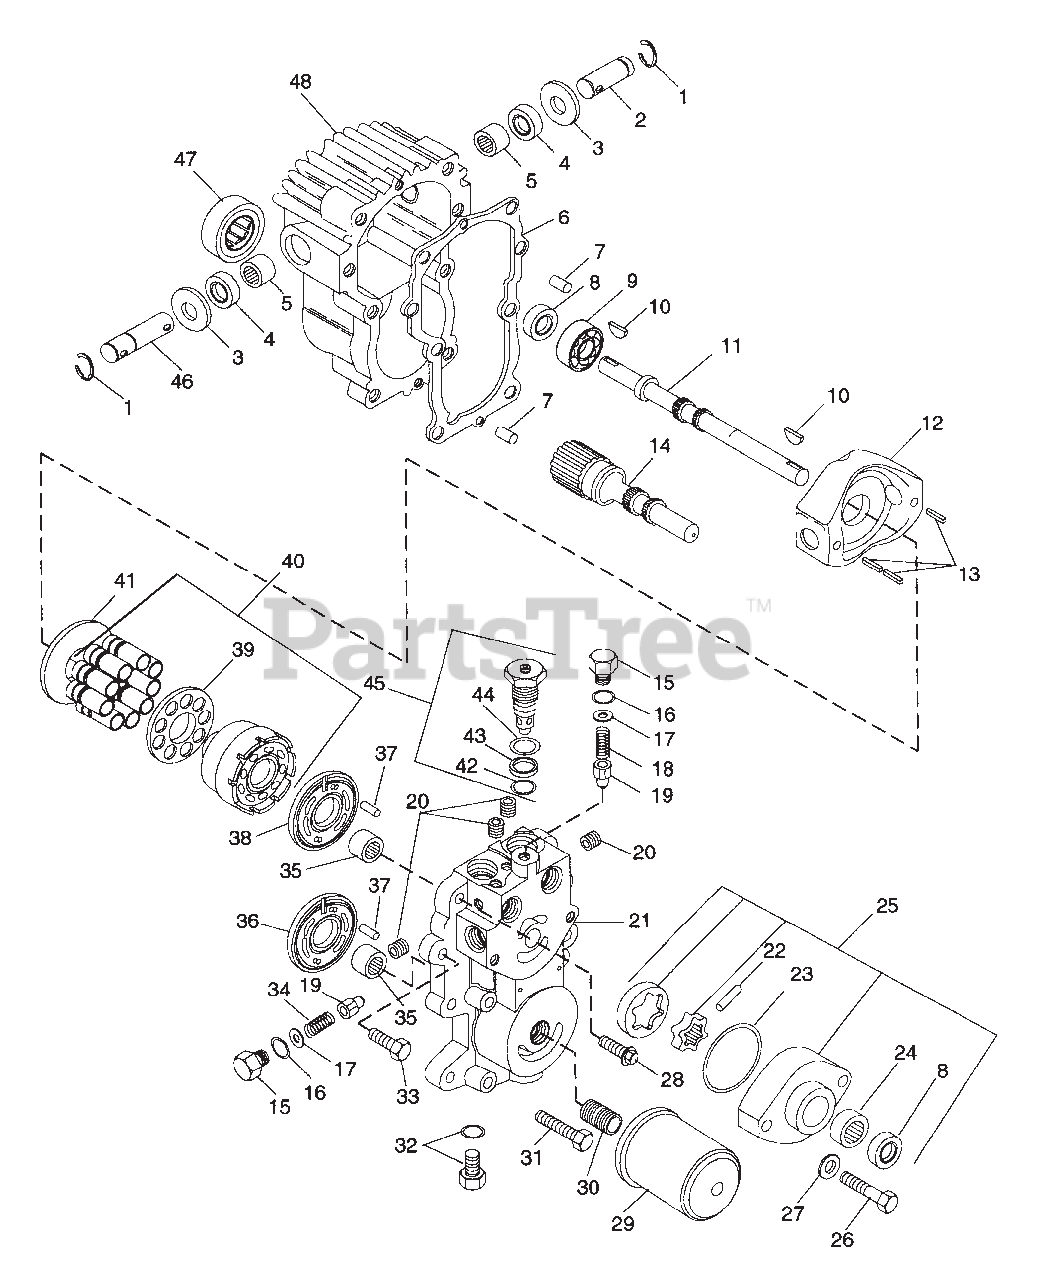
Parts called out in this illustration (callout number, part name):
1	RG-RTNG-EXT .688X.042
2	TRUNNION SHAFT
3	WSHR-FL-STL .699X1.375X.059
4	SEAL .625X1.187X.187
5	BRG-NEEDLE .688X.876X.63
7	DOWEL PIN
8	SEAL .625X1.128X.250
9	BRG-BALL 17MMX40MMX12MM
10	KEY-WDRF .188X.75X.313 SAE 9
11	PUMP SHAFT
12	SWASHPLATE VARIABLE
13	PIN-ROLL .188X.63
14	MOTOR SHAFT
15	PLUG-HEX HEAD
16	O-RING .414X.562X.072
17	SHIM PACKAGE
18	SG-COMP ??X??X?? SUNSTRAND
19	RELIEF VALVE CONE
20	PIPE PLUG
21	CENTER SECTION
23	O-RING 2.364X2.504X.072
24	BRG-NEEDLE .625X.875X.50
25	CHARGE PUMP ASSEMBLY
26	BLT-HEX .44-14X2.00 GR5
27	WSHR-FL-STL .469X.719X.108
28	SCR-12PNT .38-16X1.25 GR5
29	OIL FILTER
31	BLT-HEX .38-16X2.00 PL GR5
32	THREADED PLUG
33	BLT-HEX .38-16X1.50 PL GR5
34	SG-COMP ??X??X?? SUNSTRAND
35	BRG-NEEDLE 17MMX.938X.62
36	MOTOR VALVE PLATE
37	DOWEL PIN
38	VALVE PLATE
39	SLIPPER RETAINER
40	CYLINDER BLOCK KIT
41	THRUST PLATE
42	O-RING .614X.750X.070
43	O-RING .614X.750X.046
44	O-RING .770X.968X.097
45	CHECK VALVE ASSEMBLY
46	TRUNNION SHAFT
47	BRG-ROLLER 1.27X2.05X15MM
48	HOUSING W/SEALS AND BEARINGS
